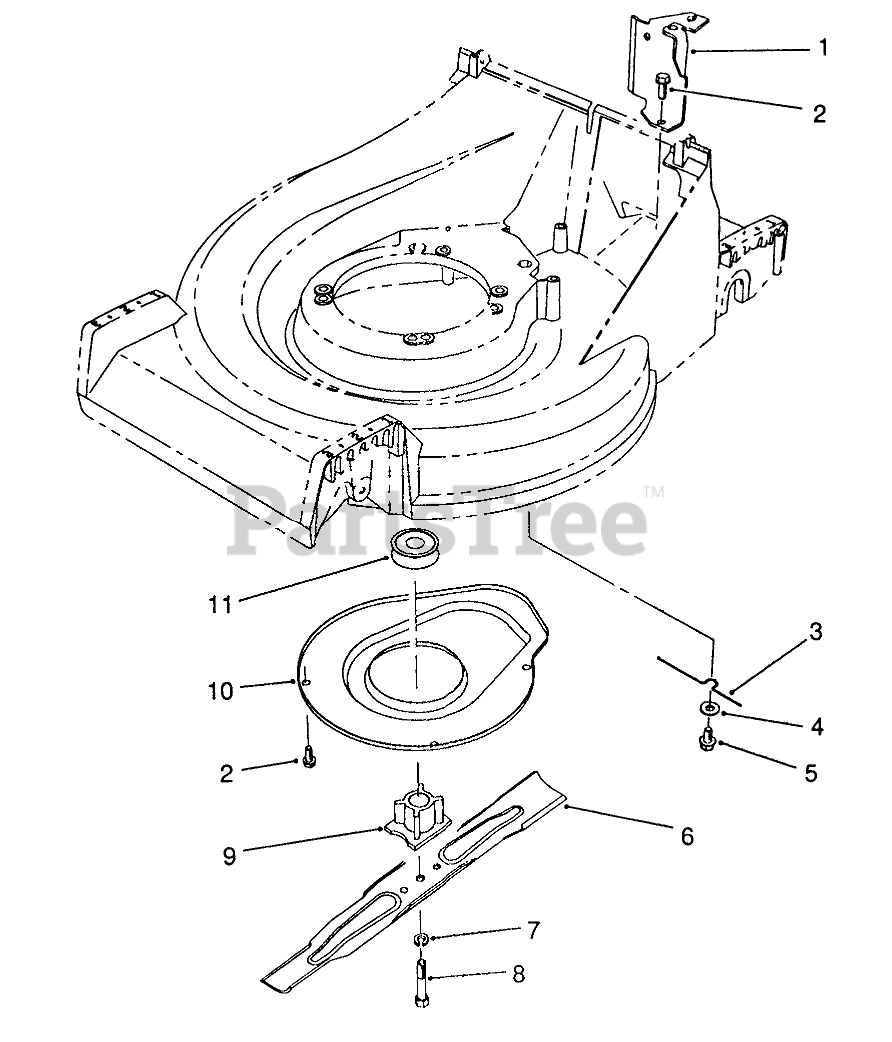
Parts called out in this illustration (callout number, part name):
1	Bracket-Cable Support
2	SCREW-HWHTF
3	RETAINER-BELT
4	WASHER-FLAT
5	SCREW-HHFTF
6	Key
7	WASHER-LOCK
8	SCREW-BLADE
9	BLADE RETAINER
10	Cover
11	PULLEY-DRIVE, ZONE START
